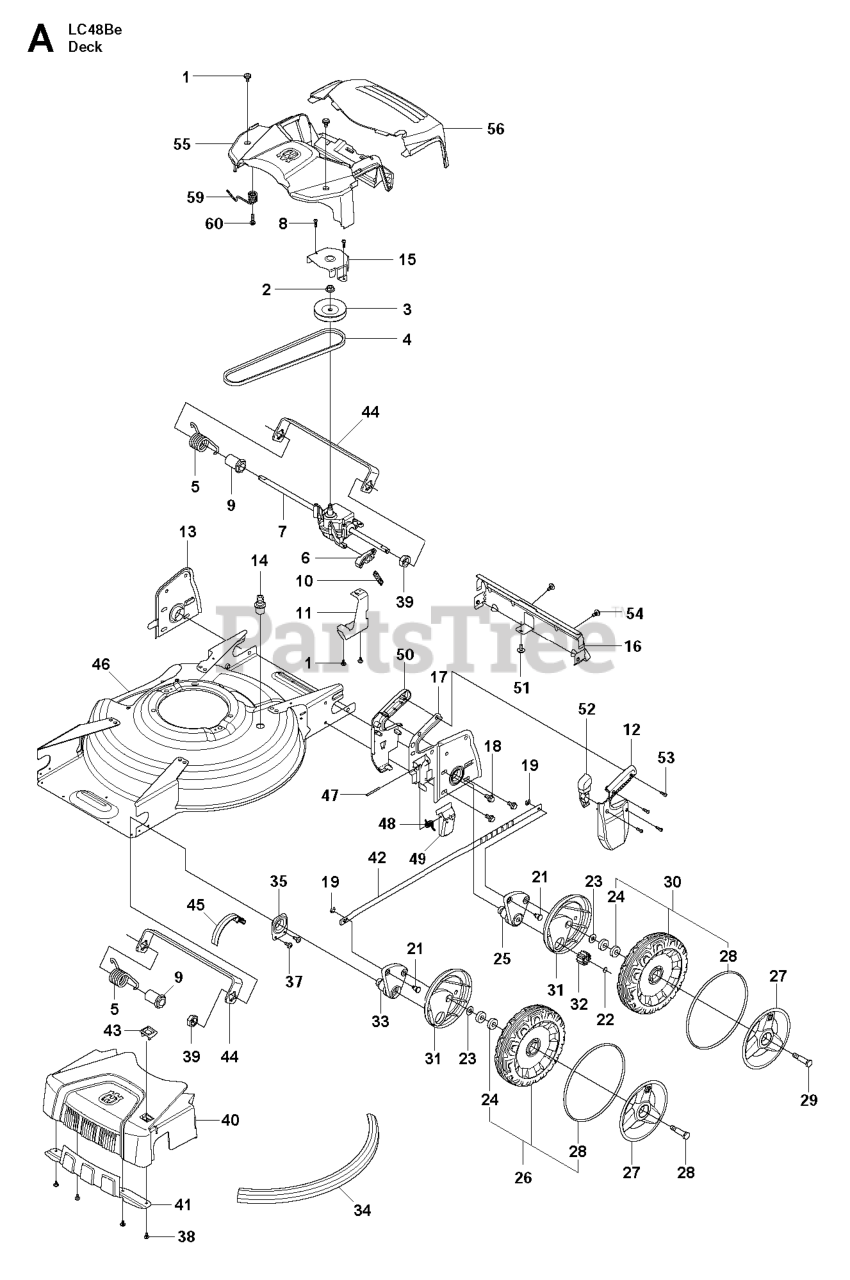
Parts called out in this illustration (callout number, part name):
1	SCREW ITXPANTT M5X10 ZPB (A00
4	BELT WRAPPED V-BELT Z 29.5
8	SCREW ITXPANT T50X16 ZN/FE (A
19	FASTENER
24	BALL BEARING
37	SCREW ITXPANTT M5X10 ZPB (A00
38	SCREW ITXPANTT M5X10 ZPB (A00
46	CHASSIS 48S A009 PAINTED
51	SCREW ITXPANTT M5X10 ZPB (A00
53	SCREW ITXPANT T50X16 ZN/FE (A
54	SCREW ITXPANTT M5X10 ZPB (A00
57	SCREW ITXPANTT M5X10 ZPB (A00
60	SCREW ITXPANT T50X16 ZN/FE (A
